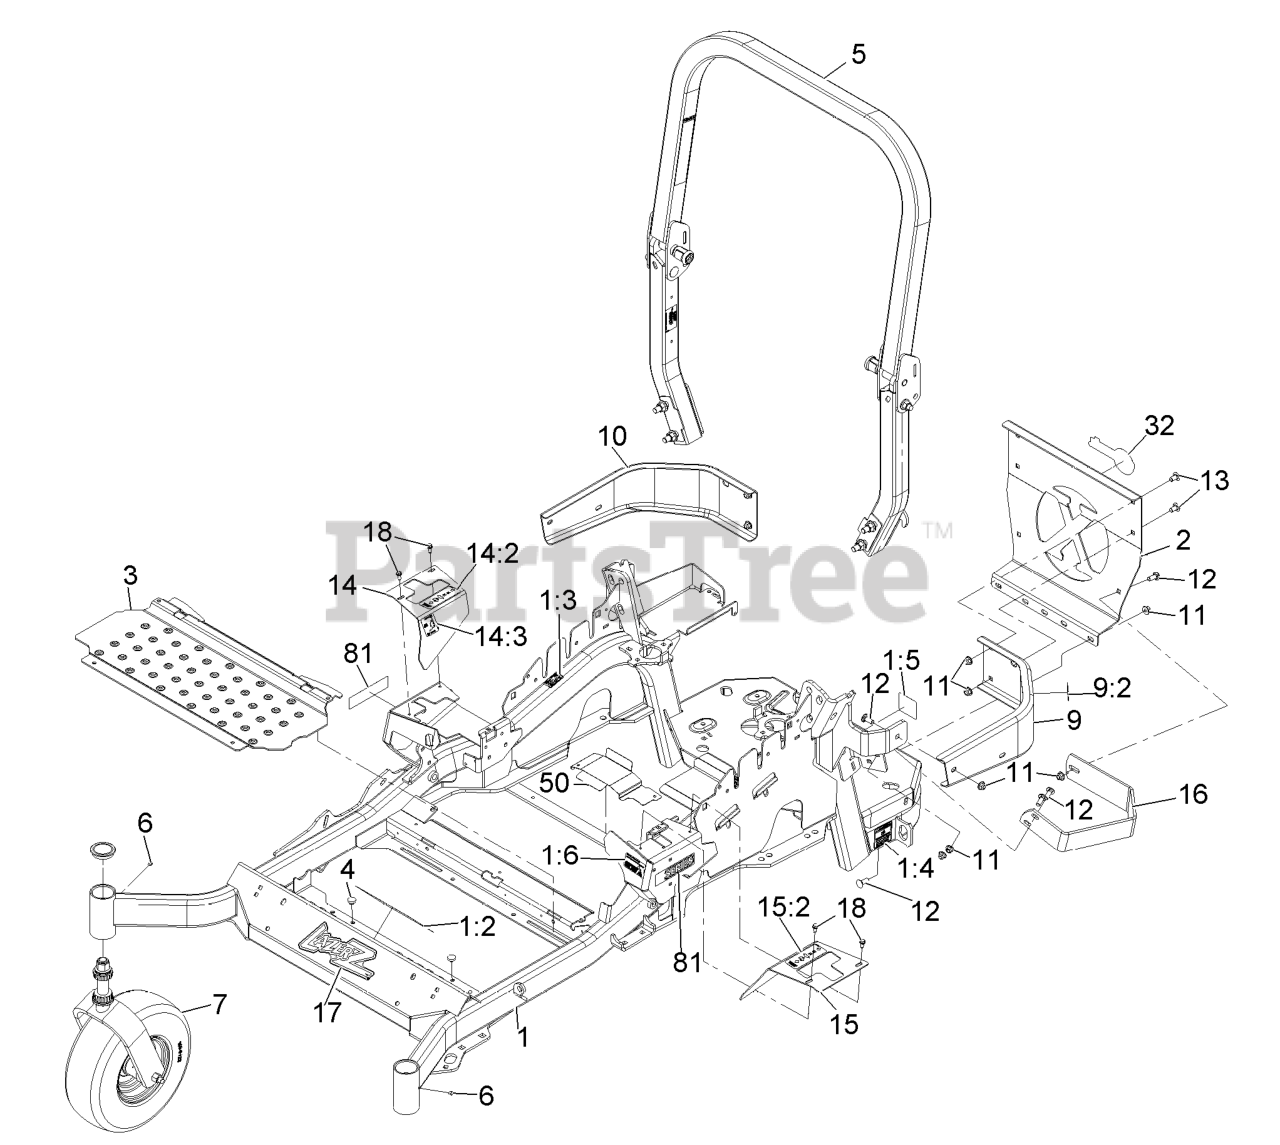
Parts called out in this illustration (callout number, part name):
1	MAIN FRAME ASM
1:2	DECAL-SLOPE
1:3	DECAL-CAUTION
1:4	DECAL-BELT DRIVE
1:5	DECAL-SPARK ARRESTER
1:6	DECAL-FUEL FILL
2	PLATE,REAR GUARD
5	ROPS ASM
7	Asm,Front Caster W/Fork
9	LH BUMPER ASM
9:2	DECAL-CAUTION
10	BUMPER-RH
11	NUT-HF, NI
12	SCREW-CARR
13	SCREW-CARR
14:2	DECAL-MOTION CONTROL
15	LH MOTION CONTROL COVER ASM
15:2	DECAL-MOTION CONTROL
17	DECAL,LAZER MODEL
18	SCREW-HWH
50	GUARD-BELT
81	DECAL-E-SERIES
